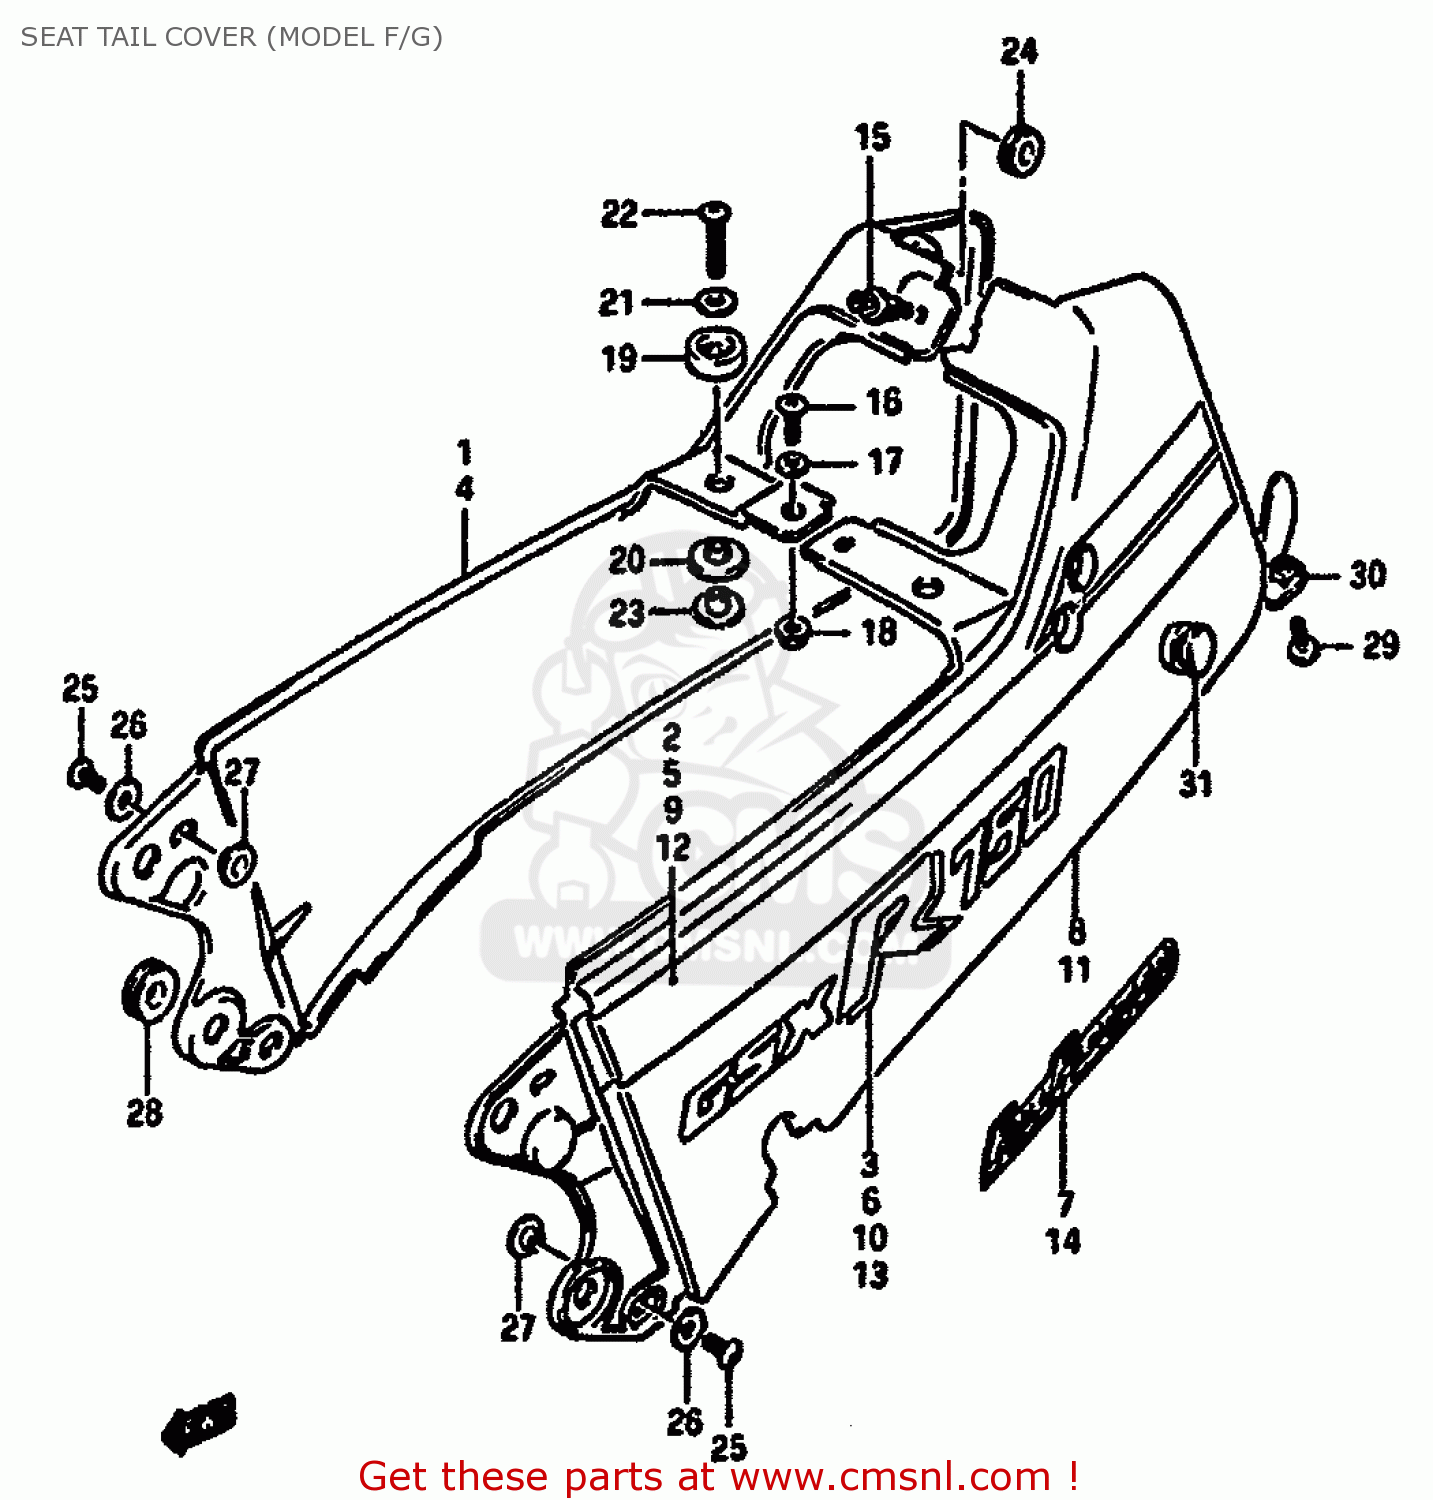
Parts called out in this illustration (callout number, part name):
1	COVER,SEAT TAIL RH
2	TAPE SET,RH
3	EMBLEM
4	COVER,SEAT TAIL
5	TAPE SET,SEAT TAIL COVER
6	EMBLEM
7	EMBLEM
8	COVER,SEAT TAIL LH
9	TAPE SET,LH
10	EMBLEM
11	COVER,SEAT TAIL
12	TAPE SET,SEAT TAIL COVER
13	EMBLEM
14	EMBLEM
15	CLIP
16	SCREW
17	WASHER
18	NUT
19	CUSHION,TAIL COVER UPR
20	CUSHION,TAIL COVER LWR
21	WASHER
22	SCREW
23	SPACER,SEAT TAIL COVER
24	CUSHION
25	SCREW
26	WASHER
27	WASHER
28	CUSHION
29	SCREW
30	PLATE,SEAT TAIL COVER,L
31	CAP,SEAT TAIL COVER
